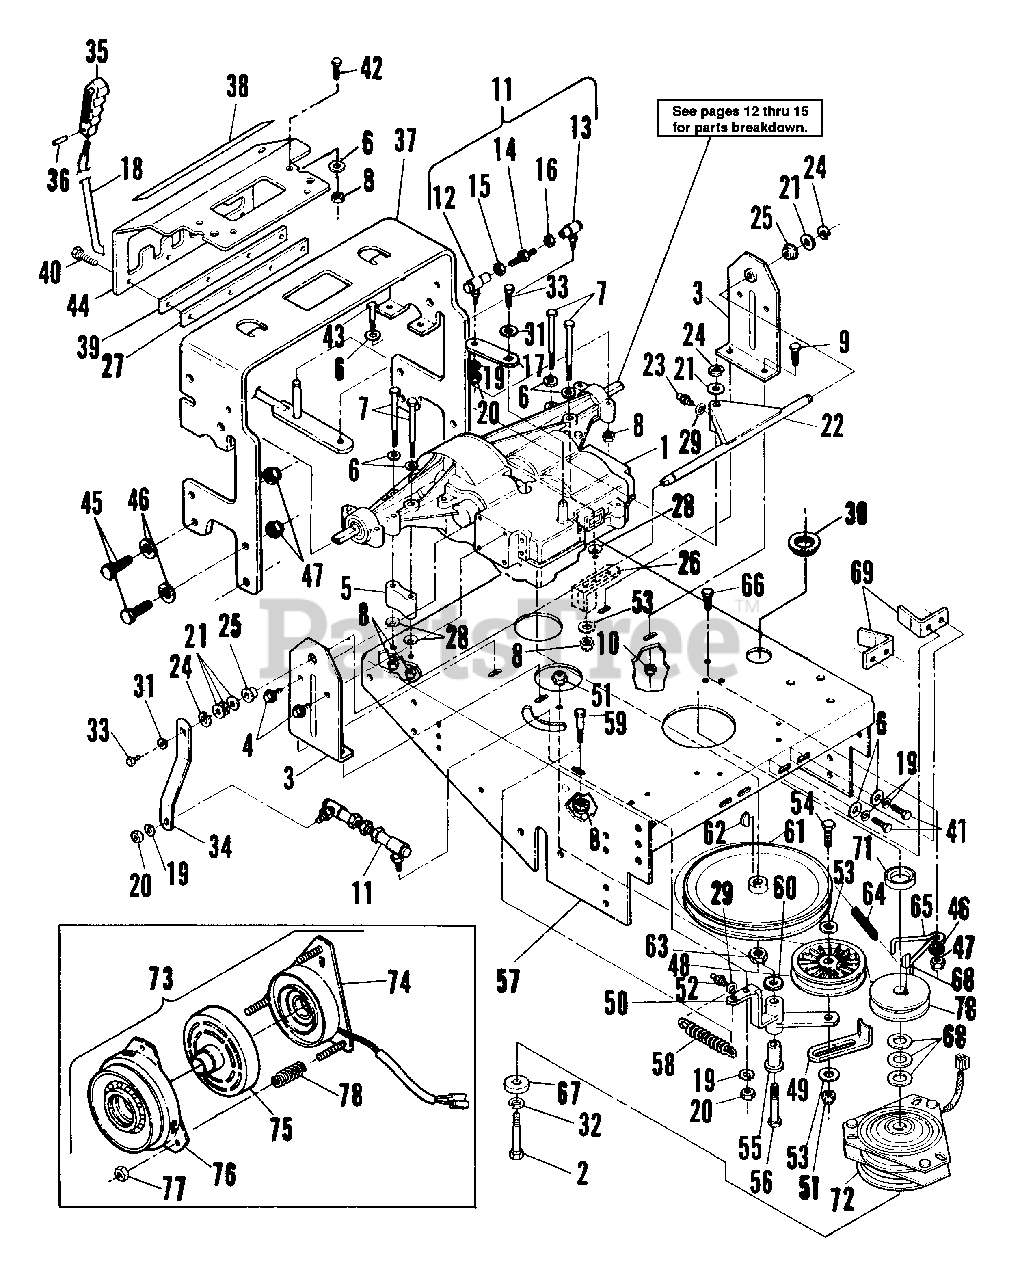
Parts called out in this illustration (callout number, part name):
1	TRANSMISSION
2	SCREW, M10-1.5 x 55 Hex Head Cap
3	MOUNT, Shift Pivot
4	SCREW, 1/4-20 x 5/8" Hex Washer Self-Tap
5	SPACER, Transmission
6	WASHER, 5/16" Flat
7	SCREW, 5/16-18 x 5" Hex Head Cap, Grade 5
8	NUT, 5/16-18 Nyloc
9	SCREW, 1/4-20 x 5/8" Hex Head Cap, Grade 5
10	NUT, 1/4-20 Hex Nyloc
11	ASSEMBLY, Linkage
12	BALL JOINT, 5/16" F,R.H.
13	BALL JOINT, 5/16" F,L.H.
14	TURNBUCKLE, 5/16" F
15	NUT, 5/16-24 Hex Jam
16	NUT, 5/16-24 Hex Jam L.H.
17	ARM, Transmission Shift
18	HANDLE, Shift
19	WASHER, 5/16" Split Lock
20	NUT, 5/16-24 Hex
21	BUSHING, Machinery, 1/2"
22	PIVOT, Transmission Shift
23	FITTING, 1/4-28 Straight, Grease
24	RING, External Retaining
25	BEARING, Nylon
26	BELT GUIDE
27	STRIP, Rubber
28	RETAINER, 5/16" Bolt
29	WASHER, 1/4" Internal Tooth Lock
30	BUSHING, Snap
31	WASHER, 1/4" Bellville
32	WASHER, 7/16" Split Lock
33	SCREW, 1/4-28 x 5/8" Hex Head Cap, Grade 5
34	ARM, Clutch
35	BALL, Knob
36	PIN, 3/16" x 3/4" Roll
37	BRACKET, Tank
38	DECAL, Shift
39	STRIP, Quadrant
40	SCREW, #10-24 x 1/2" Hex Washer Self-Tap
41	SCREW, 5/16-18 x 3/4" Hex Head Cap, Grade 5
42	BOLT, 5/16-18 x 1" Short Neck Carriage, Grade 5
43	SCREW, 5/16-18 x 2-1/2" Hex Head Cap, Grade 5
44	QUADRANT, Shift
45	SCREW, 3/8-16 x 1" Hex Head Cap, Grade 5
46	WASHER, 3/8" Flat
47	NUT, 3/8-16 Hex Nyloc
48	PULLEY, Idler
49	BELT GUIDE, Idler
50	IDLER, Transmission
51	NUT, 3/8-16 Hex Nyloc
52	FITTING, 1/4" Straight Lube
53	WASHER, 3/8" Flat
54	BOLT, 3/8-16 x 2" Hex Head, Grade 5
55	SPACER, Pivot
56	SCREW, 3/8-16 x 3-1/4" Hex Head Cap, Grade 5
57	DECK, Rear
58	SPRING, Transmission
59	BOLT, 5/16-18 Shoulder
60	BUSHING, Machinery, 1"
61	PULLEY, Transmission
62	KEY, Woodruff, #61/605
63	NUT, 5/8-18 Hex Center Lock Jam
64	BELT, Transmission
65	BELT GUIDE
66	TAP BOLT, 3/8-16 x 7/8"
67	SPACER, LT 16
68	KEY, 1/4" Square
69	STOP, Clutch
71	SPACER, Clutch
72	CLUTCH, Electric
73	KIT, Electric Clutch
74	FIELD COIL
76	ASSEMBLY, Arm-Pulley
77	NUT, 3/8-24 Hex Nyloc
78	COIL SPRING
